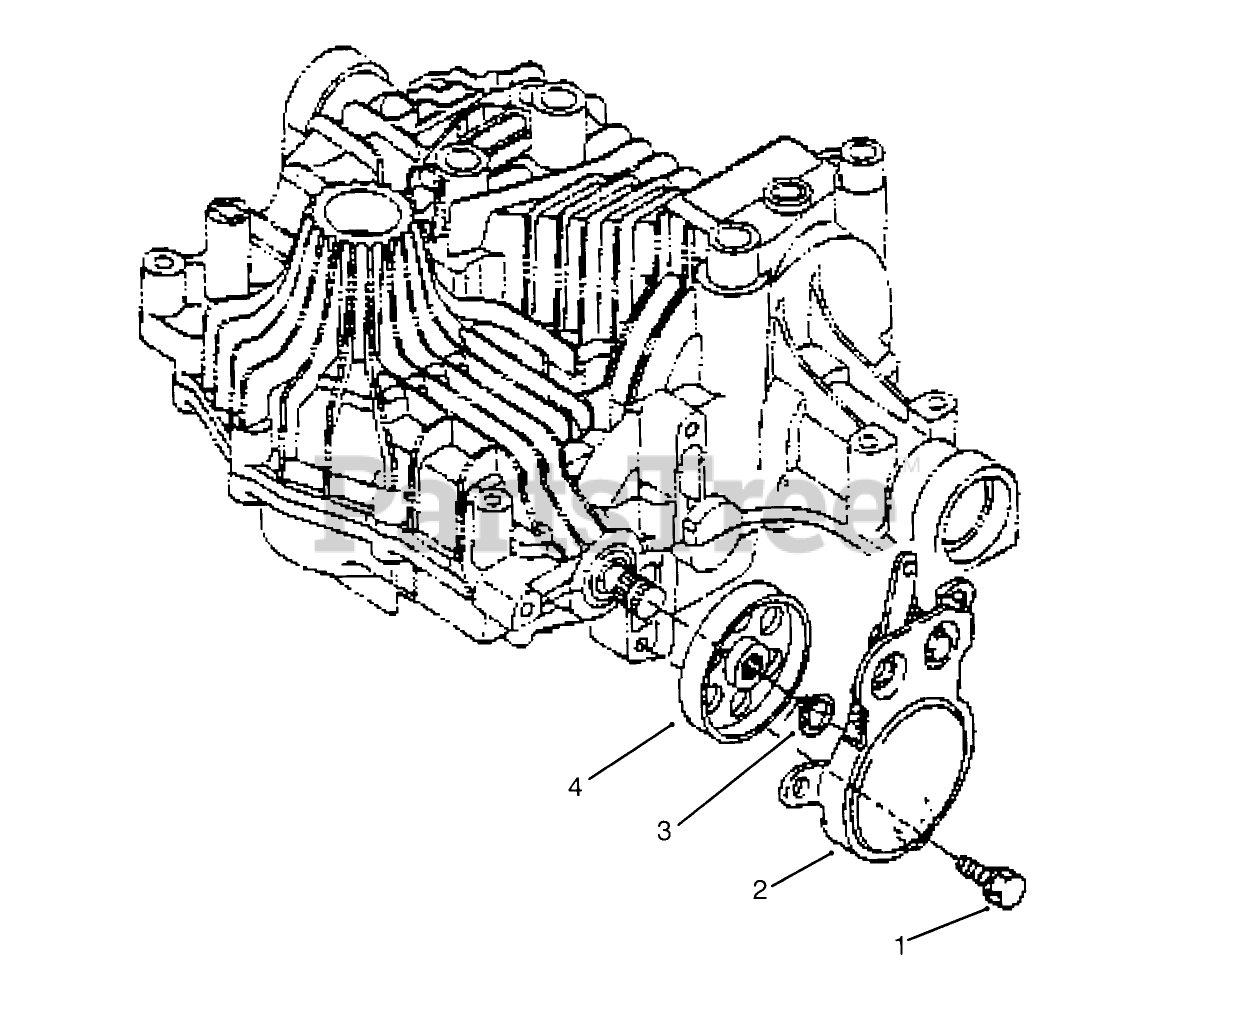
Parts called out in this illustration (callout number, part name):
1	BOLT AND WASHER ASM
3	RING-SNAP
4	DRUM-BRAKE
